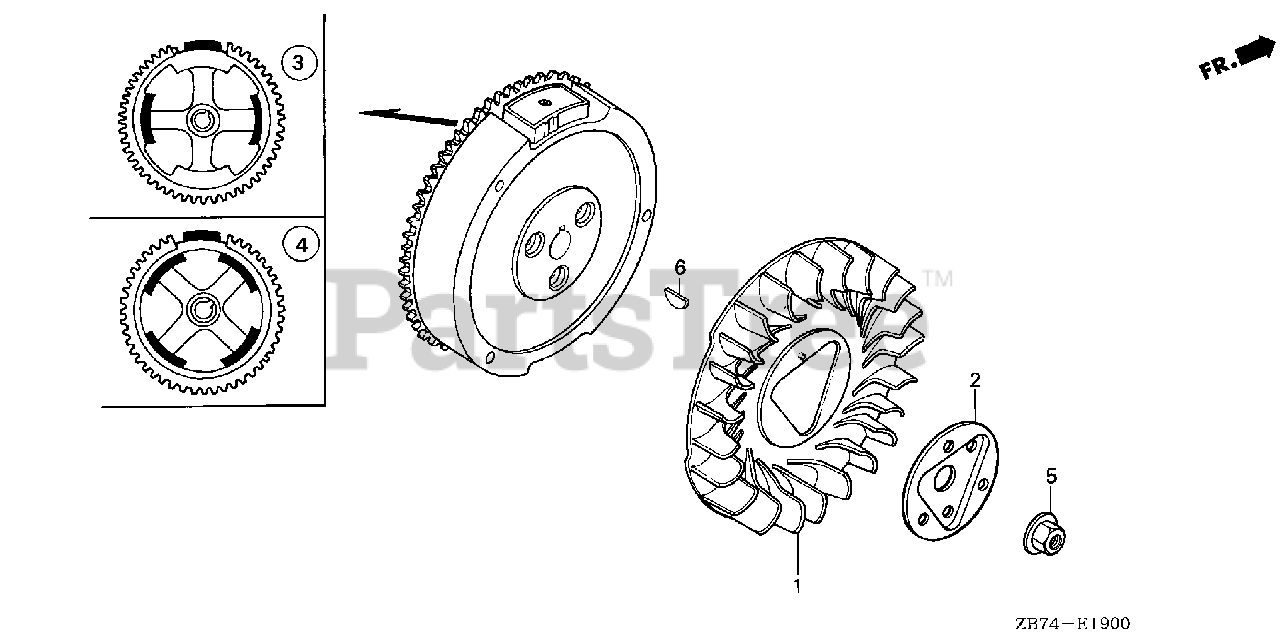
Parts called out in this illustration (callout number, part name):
1	FAN, COOLING
2	PLATE, COOLING FAN SETTING
3	FLYWHEEL (4POLE)
5	NUT, SPECIAL (16MM)
6	KEY, SPECIAL WOODRUFF (25X18)
